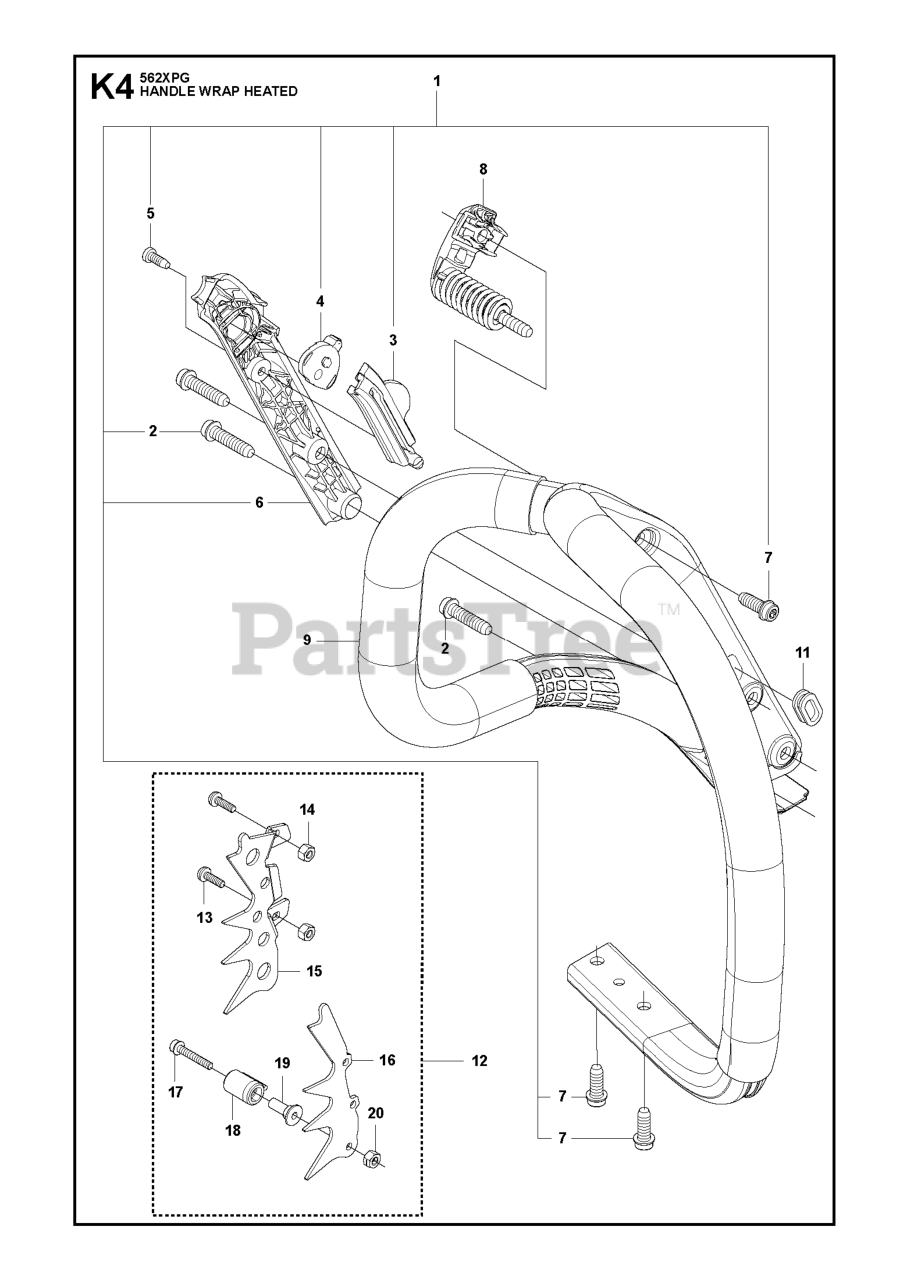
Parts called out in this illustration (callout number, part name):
1	HANDLE KIT WRAP
3	CONTACT PLATE
5	SCREW CITXPANT
7	SCREW ITXSCFT PL6X16 T27 10.9
8	ANTIVIBRATION ELEMENT CYLINDER
12	SPIKE ASSY KIT
13	SCREW ITXPANM M5X16 T27 10.9
15	SPIKE, OUTER
16	SPIKES, INNER
19	CHAIN CATCHER
